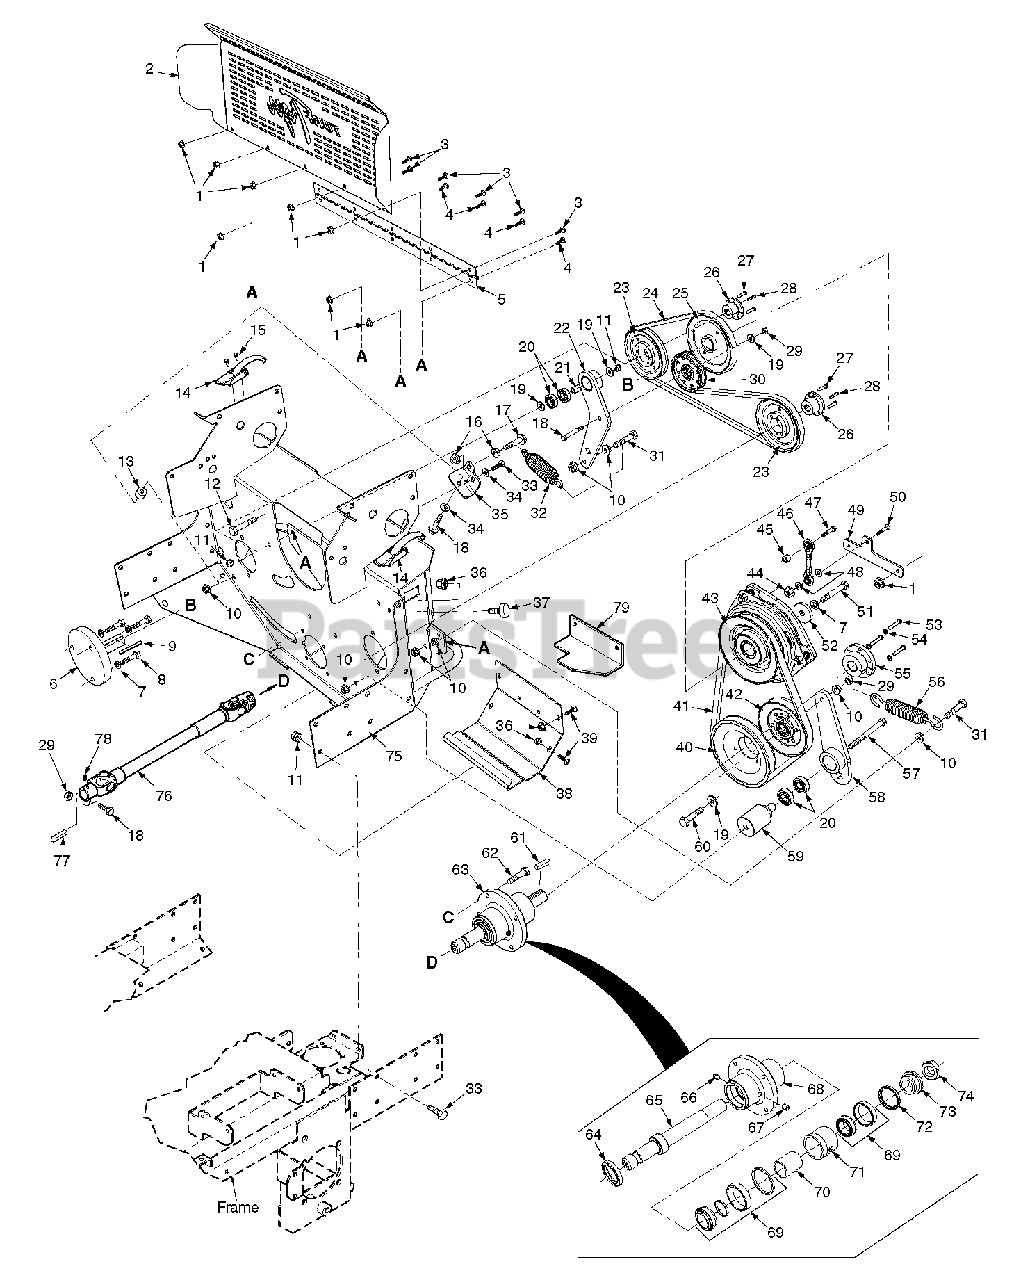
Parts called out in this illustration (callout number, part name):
1	Nut, Serrated Flange 1/4-20
2	Belt Guard, Rear
3	Bolt, Carriage 1/4-20 x 1/2"
4	Bolt, Carriage 1/4-20 x 3/4"
5	Hinge, Belt Guard
6	Stub Shaft
7	Lockwasher, 7/16" Spring
8	Bolt, Hex Head M10 x 1.5 x 35
9	Key, 1/4 x 1/4 x 3-1/4"
10	Nut, Serrated Flange 3/8-16
11	Nut, Elastic Stop 3/8-16
12	Bolt, Hex Head 3/8-16 x 1-3/4" Grd 8
13	Spacer
14	Latch, Hood
15	Screw, #10-32 x .56
16	Nut, Serrated Flange 1/2-13
17	Bolt, Hex Head 1/2-13 x 2" Grd 8
18	Bolt, Hex Head 3/8-16 x 1-3/4"
19	Washer, 3/8" Hardened
20	Ball Bearing
21	Spacer, Idler Bearing
22	Idler Arm Weldment, Pump Drive
23	Pulley, 5.75" O.D.
24	Belt, Pump Drive
25	Pulley, 6.35 Dia. - 1.125 Bore
26	Tapered Hub, 17mm Bore
27	Bolt, Hex Head 1/4-20 x 1" Grd 8
28	Key, 5 x 5 x 35 mm
29	Nut, Center Lock 3/8-16
30	Pulley, Idler 4" Dia.
31	Bolt, Hex Head 3/8-16 x 1-1/2" Grd 8
32	Spring, Transmission Idler
33	Bolt, Hex Head 3/8-16 x 1"
34	Flatwasher, 3/8-.391 x .938 x .105
35	Bracket
36	Nut, Serrated Flange 5/16-18
37	Bumper, Rubber
38	Cover, Rear
39	Bolt, Carriage 5/16-18 x 3/4"
40	Pulley, 6.35 Tapered Bore
41	Belt, Deck Drive
42	Pulley, Idler 5" Dia.
43	Clutch, Ogura GT 3.5 - 1.125 Bore
44	Nut, Hex Elastic Stop 5/16-18
45	Spacer
46	Rod Assembly, Clutch Anti-Rotation
47	Bolt, Hex Head 5/16-18 x 1-1/2"
48	Flatwasher, 5/16"
49	Bracket, Anchor, Anti-Rotation
50	Bolt, Hex Head 5/16-18 x 1-1/4"
51	Bolt, Hex Head 7/16-20 x 2-1/4"
52	Flatwasher, 7/16-.469 x 1.75 x .25
53	Bolt, Hex Head 1/4-20 x 1-3/8"
54	Lockwasher, 1/4" Spring
55	Tapered Hub, 1" Bore
56	Spring, PTO
57	Bolt, Hex Head 3/8-16 x 4-1/2" Grd 8
58	Idler Arm Weldment, PTO Drive
59	Pivot, Idler PTO
60	Bolt, Hex Head 3/8-16 x 2-1/2" Grd 8
61	Key, 1/4 x 1/4 x 1-1/2"
62	Bolt, Hex Head 5/16-18 x 1-3/4" Grd 8
63	Spindle Assembly, Deck Drive
64	Seal, 2.0 OD x 1.5 Bore
65	Shaft, Deck Drive
66	Grease Fitting, 1/4-28
67	Relief Fitting
68	Spindle Housing
69	Roller Bearing Tapered
70	Spacer, Inside
71	Spacer, Outside
72	Seal, 2.0 OD x 1.625 Bore
73	Spindle Bushing, Bottom
74	Nut, 1.06-18 Thread
75	Pump Mounting Plate Weldment
76	Driveshaft
77	Key, 1/4 x 1/4 x 1"
78	Set Screw, 3/8-16 x 3/4" Torx Socket
79	Bracket, Idler Stop
